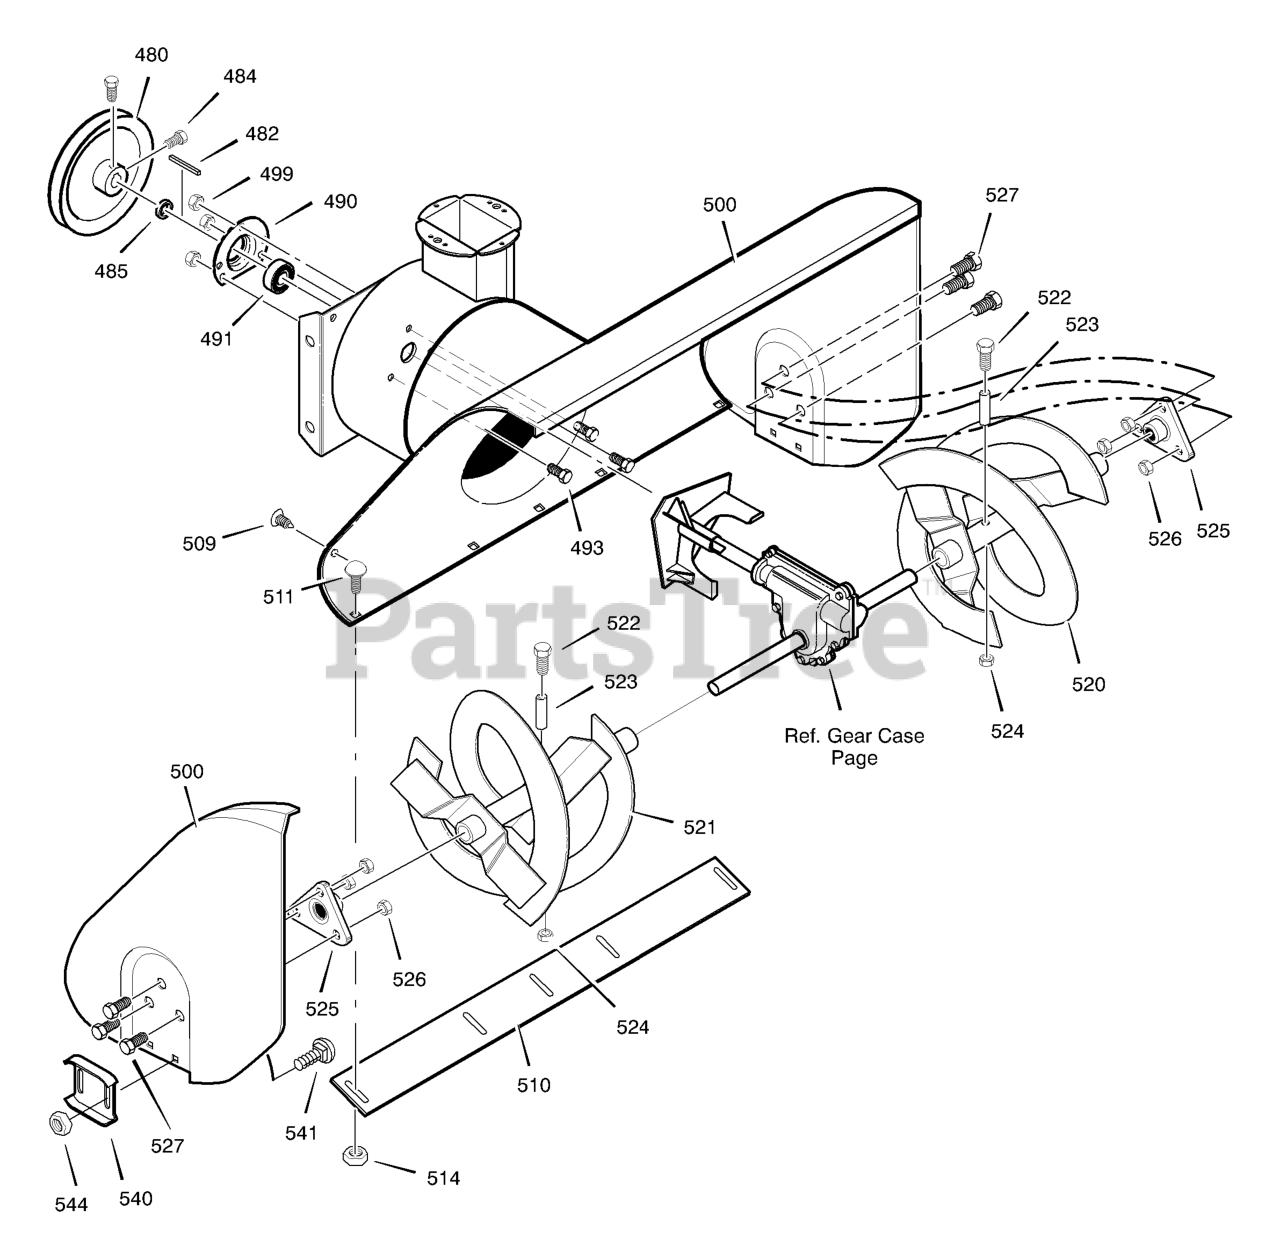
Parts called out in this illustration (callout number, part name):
482	KEY, SQUARE
484	SCREW, 5/16-18 x 0.63
485	SPACER, FRICTION PULLEY
490	RETAINER, BALL BRNG
491	BEARING, BALL
493	BOLT, HEX - 0.31-18X0.50
499	NUT, 5/16-18 HEXWDFLLK
500	HOUSING, ASSY
509	PLUG, CHRISTMAS TREE
510	BLADE, SCRAPER
511	BOLT, 1/4-20X.75
520	AUGER, ASSY, LH
521	AUGER, ASSY, RH
522	SCREW, 1/4-20X1.75
523	SPACER, SLEEVE
524	NUT, 1/4-20
525	BEARING, FLANGE
526	NUT, TOPLOCK 5/16-18
527	SCREW, 5/16-18 x 0.75
540	SKID, HEIGHT ADJUST
541	BOLT, 5/16-18 X .75
544	NUT, 5/16-18 REGHEX
